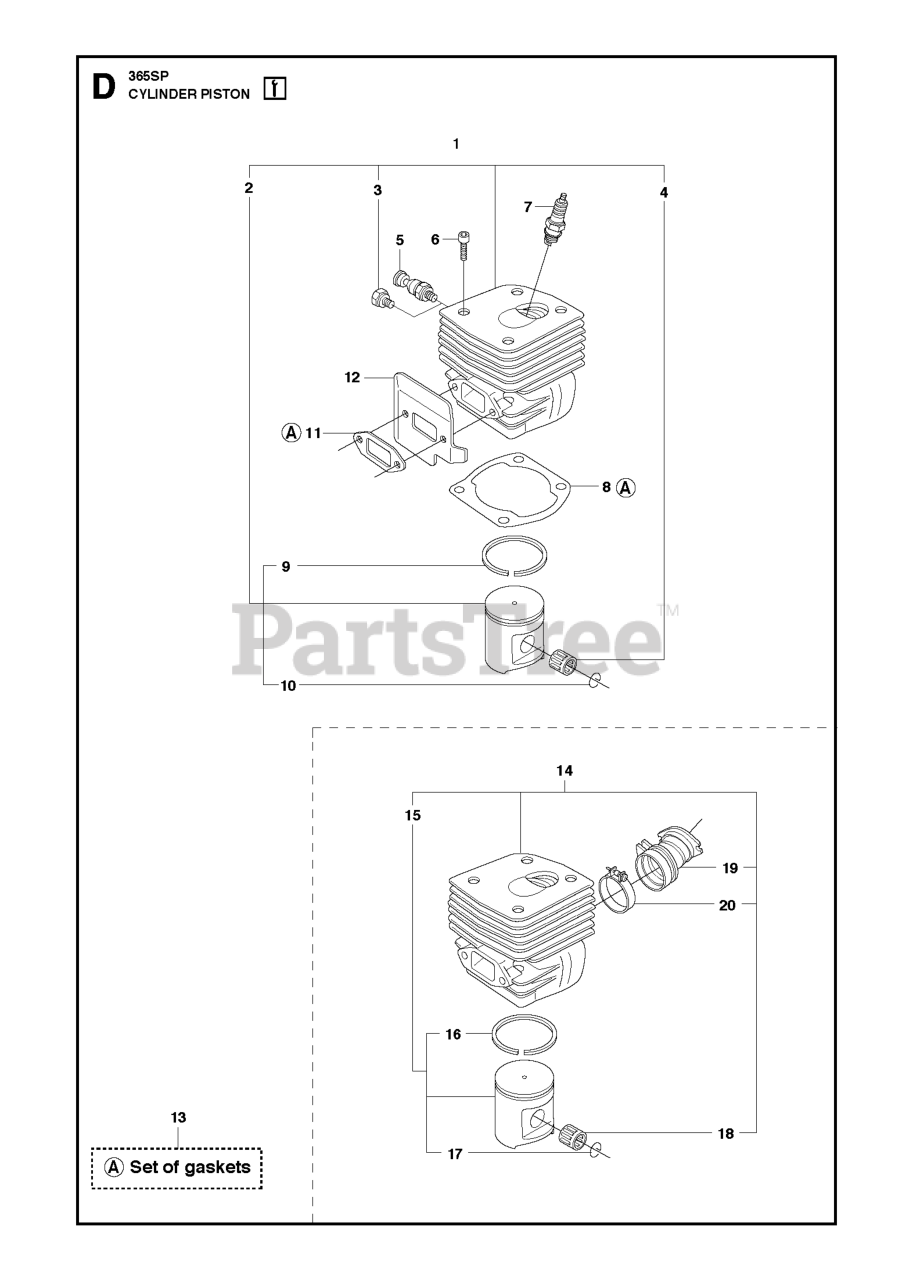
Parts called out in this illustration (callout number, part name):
1	CYLINDER ASSY
2	PISTON CPL 48 MM
3	CYLINDER PLUG
4	NEEDLE BEARING PISTON PIN 12X1
5	DECOMPRESSION VALVE
6	SCREW ITXSCM M5X25 T27 12.9 T
7	SPARK PLUG M14X1.25 NGK BPMR7A
9	PISTON RING
10	WRIST PIN CLIP
13	GASKET SET
14	CYLINDER
15	PISTON CPL 48 MM
16	PISTON RING
17	WRIST PIN CLIP
18	NEEDLE BEARING PISTON PIN 12X1
19	INTAKE PIPE - EPA
20	CLAMP
